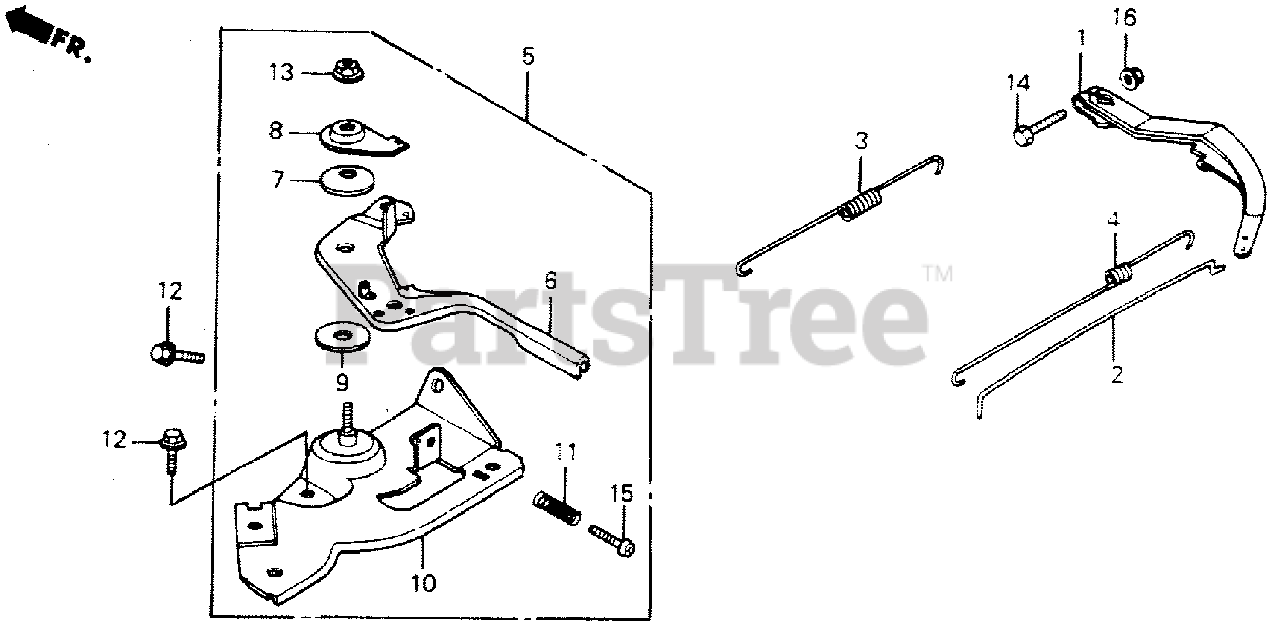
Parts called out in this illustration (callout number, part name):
1	ARM, GOVERNOR
2	ROD, GOVERNOR
3	SPRING, GOVERNOR
4	SPRING, THROTTLE RETURN
5	CONTROL ASSY.
6	LEVER, CONTROL
7	SPRING, LEVER
8	WASHER, CONTROL LEVER
9	SPACER, CONTROL LEVER
10	BASE, CONTROL
11	SPRING, CONTROL ADJUSTING
12	BOLT, FLANGE (6X12) (CT200)
13	NUT, SELF-LOCK (6MM)
14	BOLT, GOVERNOR ARM
14	BOLT, HEX. (6X20)
15	SCREW, PAN (5X20)
15	SCREW, PAN (5X25)
16	NUT, FLANGE (6MM)
